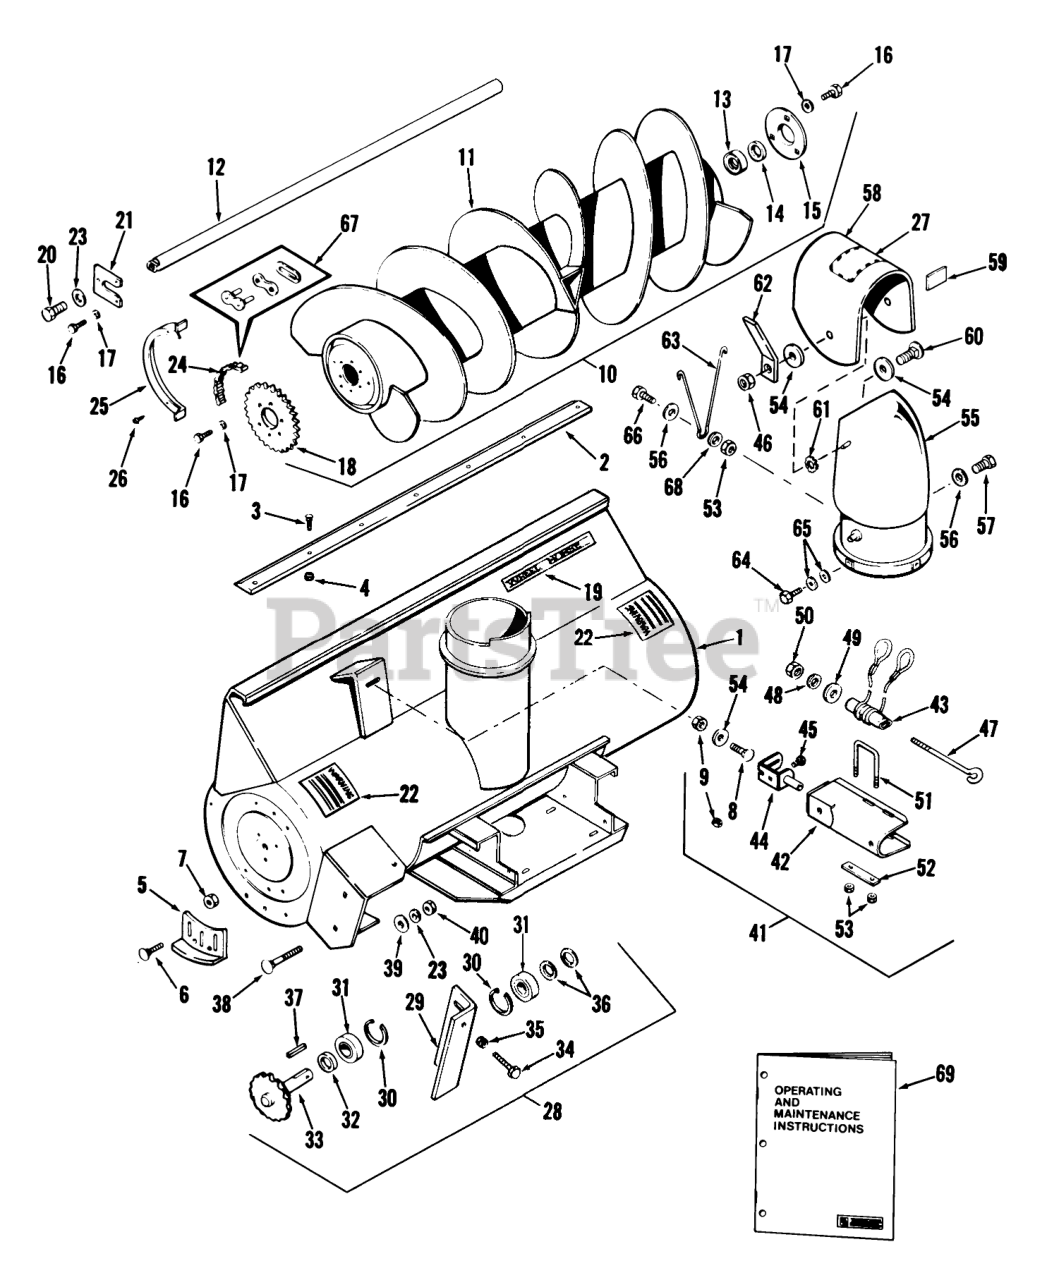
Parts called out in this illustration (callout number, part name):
1	Assembly-Header Housing
1	Assy.-Header Hsg. 48"
2	Blade-Scraper
3	Bolt 1/4-20 X 5/8
4	Nut 1/4-20
5	Shoe-Skid
6	Bolt
7	Keps Nut 5/16-18
8	Bolt
10	Auger Assembly
11	Auger
12	Auger Shaft
13	Bearing
14	Washer
15	Spring
16	Bolt
17	Lockwasher
18	Control Rod-Traction
19	DECAL-WHEEL HORSE
20	Bolt
21	PLATE AUGER MOUNTING
22	Decal
23	Lockwasher
24	Auger Drive Chain #40
24	CHAIN-AUGER DRIVE
25	Chain Guard
26	SCREW
27	Decal-Caution
28	Jackshaft Assembly
28	Spacer
28	Jackshaft Housing w/Bearings
29	Jackshaft Housing
30	Ring-Snap
31	BEARING-GEAR BOX
32	Spacer
33	Jackshaft and Sprocket
34	S.T. Bolt 5/16-18 x 2
35	Jam Nut 5/16-18
36	WSHR SPROCKET TO BRG
38	Carriage Bolt 1/2-13 x 3 1/2
39	Washer 1/2 SAE
40	Eslok Nut
41	Stack Drive Bracket
42	SHROUD-STACK DRIVE
43	ASSEMBLY CABLE
44	Bracket and Tube
45	Bolt-Carriage
46	Nut
47	EYE BOLT DRIVE TUBE
48	Spring Washer
49	Washer
50	NUT
51	U-BOLT
52	Friction Strap
53	Nut
54	WASHER
55	Elbow and Pivot Assembly
56	Washer
57	Bolt
58	Deflector Elbow
59	MOLDING DEFLECTOR
60	Bolt-Carriage
61	Washer 5/16 (Special Locking)
62	STRAP-LOCKING
63	Spring Hook
64	H H C S
65	Washer
66	Bolt
67	Chain Repair Kit
68	Spacer
69	Operating and Maintenance Instructions
